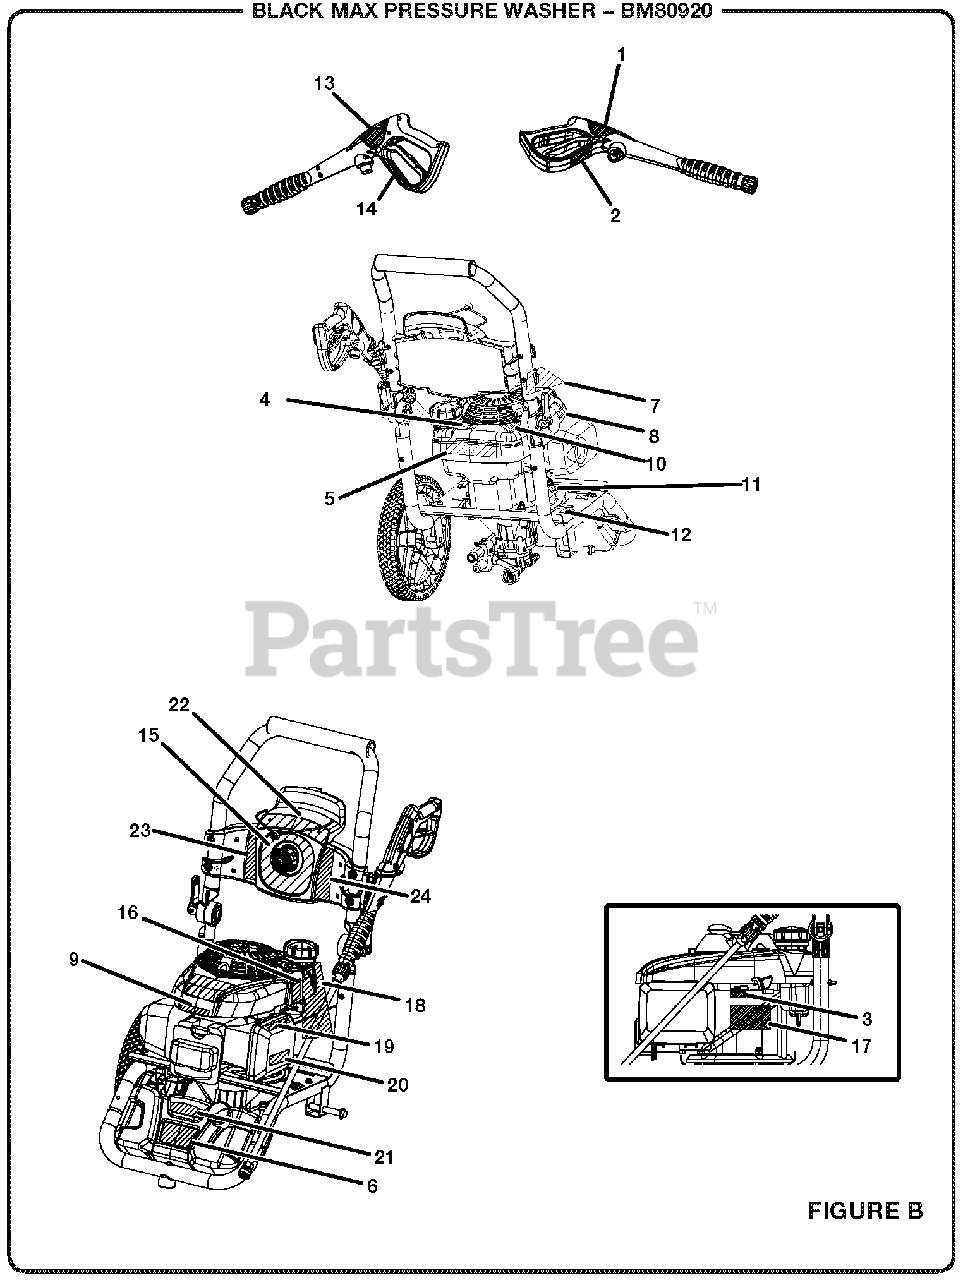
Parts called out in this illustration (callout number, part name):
1	Label (Wand Logo)
2	Warning Label (Fr/Sp)
3	Quick Start Label
4	E85 Label
5	Warning Label
6	Honda Label
7	Nozzle Hang Tag
8	Hot Surface Label
9	Honda Brand Label
10	Combustion Warning Label
11	Lubricant Hang Tag
12	Label (Engine Lubricant)
13	Label (Wand Warning)
14	Label (Wand Rating)
15	Nozzle Label
16	Do Not Mix Label
17	Release Water Label
18	Danger Hang Tag
19	Inquiries Label
20	EMC Label
21	Soap Dilution Label
22	Black Max Logo Label
23	Performance Label (2800 PSI)
24	Performance Label (2.3 GPM)
